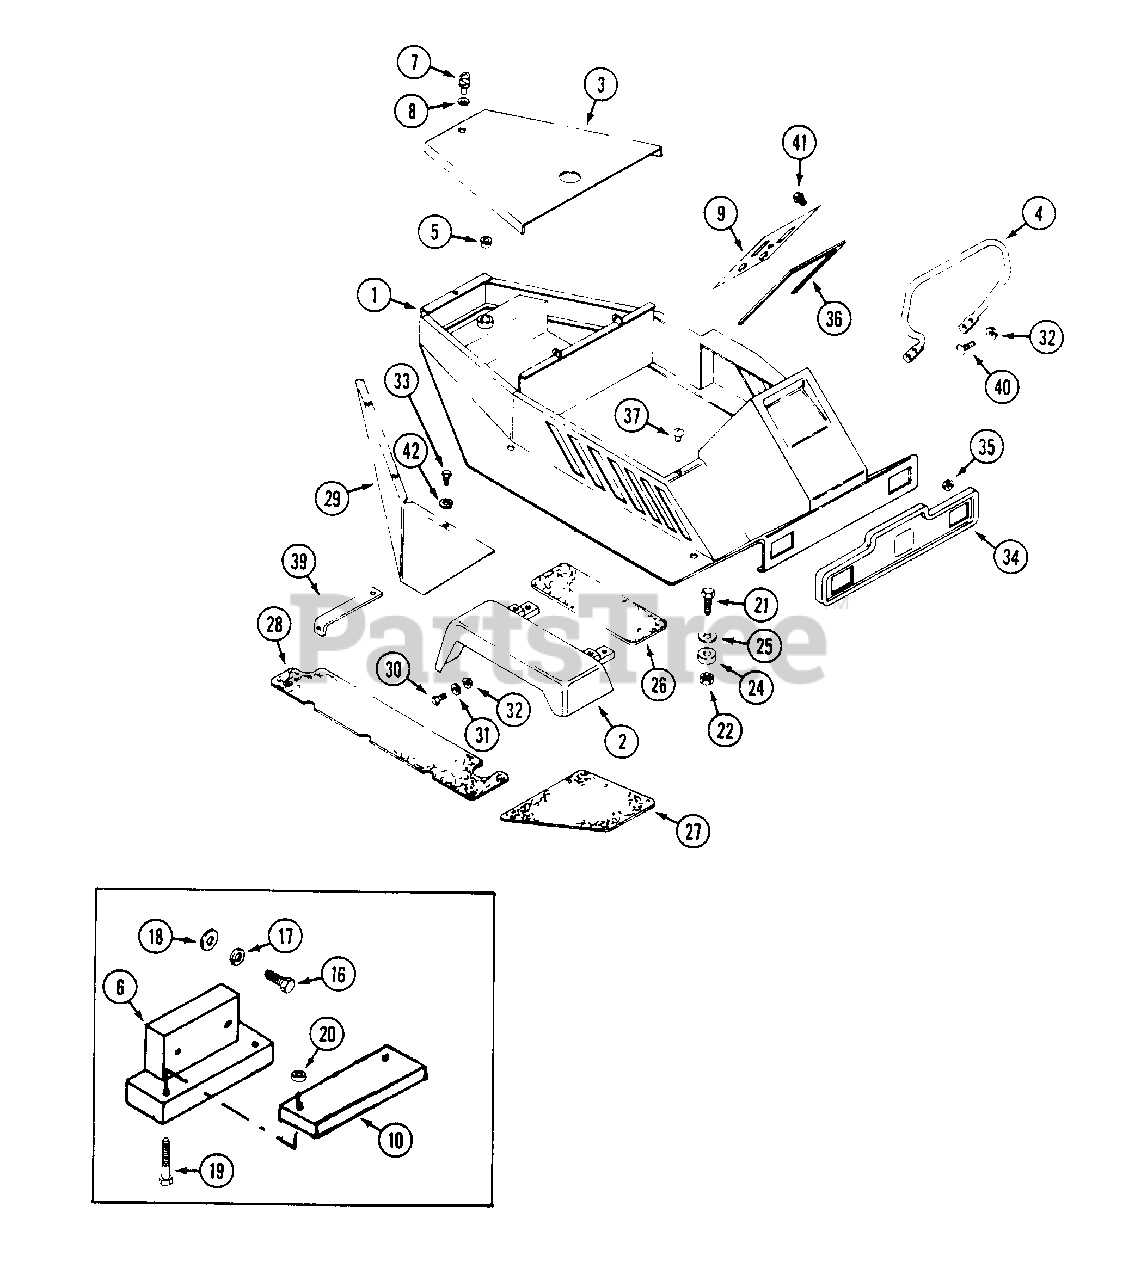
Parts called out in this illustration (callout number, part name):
1	BODY
2	FENDER - R H.
4	BAR - handle
5	BEARING - rear wheel fork
7	STUD - fastener
8	GROMMET - fastener
10	WEIGHT - tail 13 lb.
16	BOLT - 5/16" - 18 x 1"
17	LOCKWASHER - 5/16"
18	WASHER - 5/16"
19	BOLT - 3/8" - 16 x 4-1/2"
20	NUT - 3/8" - 16 flange lock
21	BOLT - 1/2" - 13 x 3"
22	NUT - 1/2" lock
24	MOUNT - body, rubber
25	WASHER - mount, body
27	PAD - footrest, front L H
28	PAD - footrest, rear L.H
30	BOLT - 5/16" - 18 x 5/8"
31	WASHER - 5/16"
32	NUT - 5/16" - 18 flange lock
33	BOLT - 5/16" - 18 x 5/8" black
35	NUT - #8 - 32 flange lock
36	TRIM - 27" (cut to length)
37	BUMPER - nylon
39	BRACKET - fender support
40	BOLT - 5/16" - 18 x 3/4" carriage
41	SCREW - #12 x 1/2"
42	LOCKWASHER - 1/4"
